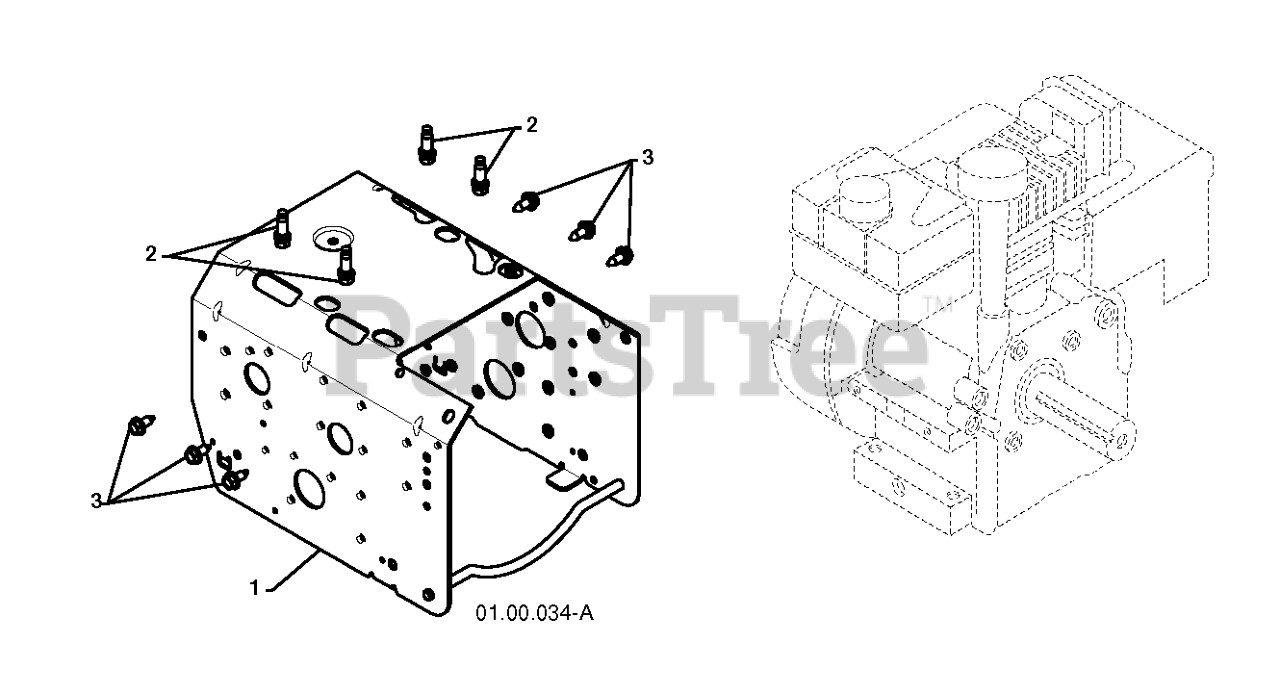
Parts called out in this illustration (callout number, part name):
1	Complete LCT Engine
1	FRAME.WELD.PNT.CHAIN.ORANGE
2	BOLT 3/8-16X1-1/8
3	BOLT.HEX.HD.WASHER.5/16-18X.75
